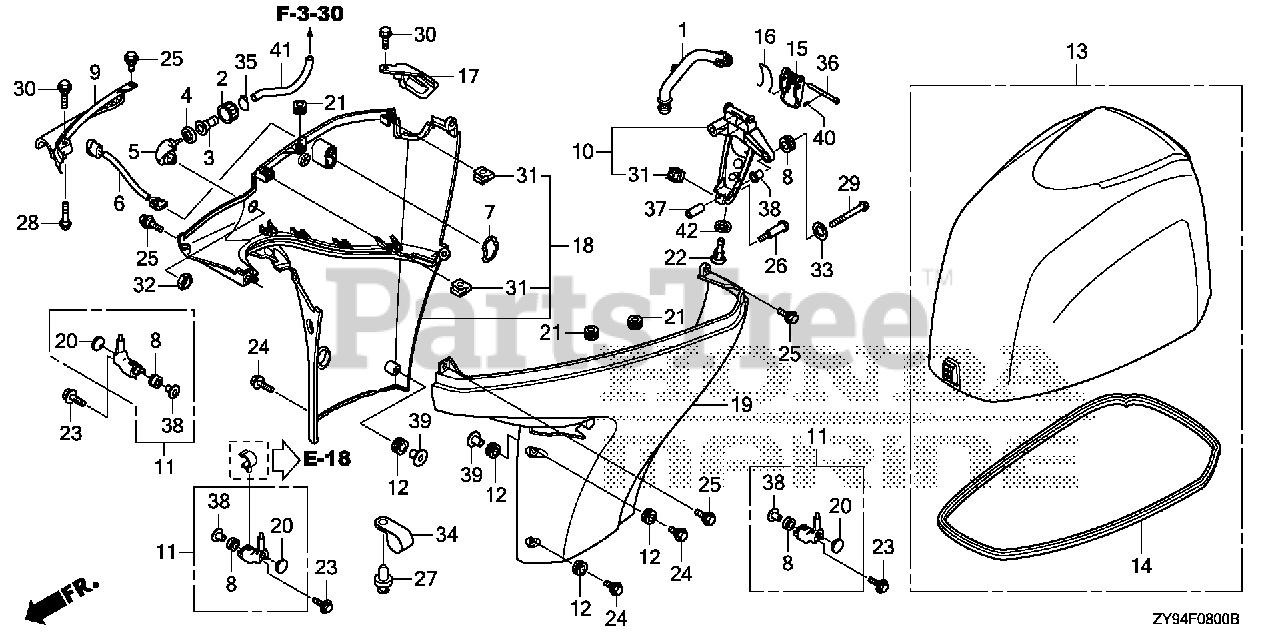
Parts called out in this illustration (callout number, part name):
1	PORT, IDLE EX.
2	NUT, WATER MOUTH
3	JOINT, WATER HOSE
4	SEAT, WATER MOUTH
5	CAP, WATER JOINT
6	SWITCH ASSY., POWER TILT
7	STAY, POWER TILT SWITCH
8	GROMMET, CASE (LOWER)
9	COVER, FR. SEPARATE *NH282MU* (OYSTER SILVER METALLIC-U)
10	BRACKET, COVER (LOWER)
11	STOPPER ASSY., ENGINE SIDE
12	RUBBER, FENDER MOUNTING
13	COVER ASSY., ENGINE *NH282MU* (OYSTER SILVER METALLIC-U)
14	SEAL, ENGINE COVER
15	LEVER, FASTENER
16	WIRE, FASTENER
17	COVER, PLUG MAINTENANCE *NH282MU* (OYSTER SILVER METALLIC-U)
18	COVER, R. ENGINE (LOWER) *NH282MU* (OYSTER SILVER METALLIC-U)
19	COVER, L. ENGINE (LOWER) *NH282MU* (OYSTER SILVER METALLIC-U)
20	RUBBER, SEAT SIDE
21	GROMMET, ENGINE COVER
22	GROMMET, WATER CHECK
23	BOLT-WASHER (6X27) (CT200)
24	BOLT-WASHER (6X22)
25	BOLT, SPECIAL (6X17)
26	BOLT, RR. BRACKET
27	SCREW, RIVET (5X10)
28	BOLT, SPECIAL (6X37)
29	BOLT, FLANGE (6X55)
30	BOLT, FLANGE (6X20) (SH)
32	NUT, HEX. (16MM) DUAL QTY = (2) (SINGLE)
33	WASHER, PLAIN (6MM)
34	CLIP (10.7MM)
35	CLIP B1, TUBE
36	PIN (5X59)
37	COLLAR, DISTANCE (6.5X11X27)
38	COLLAR, MODULE IGNITION CONTROL CASE (CDI)
39	COLLAR, DISTANCE (6.2X7.5)
40	PIN, SPRING (2.0X12)
40	PIN, SPRING (2X12)
41	BULK HOSE, FUEL (8X1000) (95001-80001-(95001-80001-60M)
42	SEAL, WATER CHECK GROMMET
